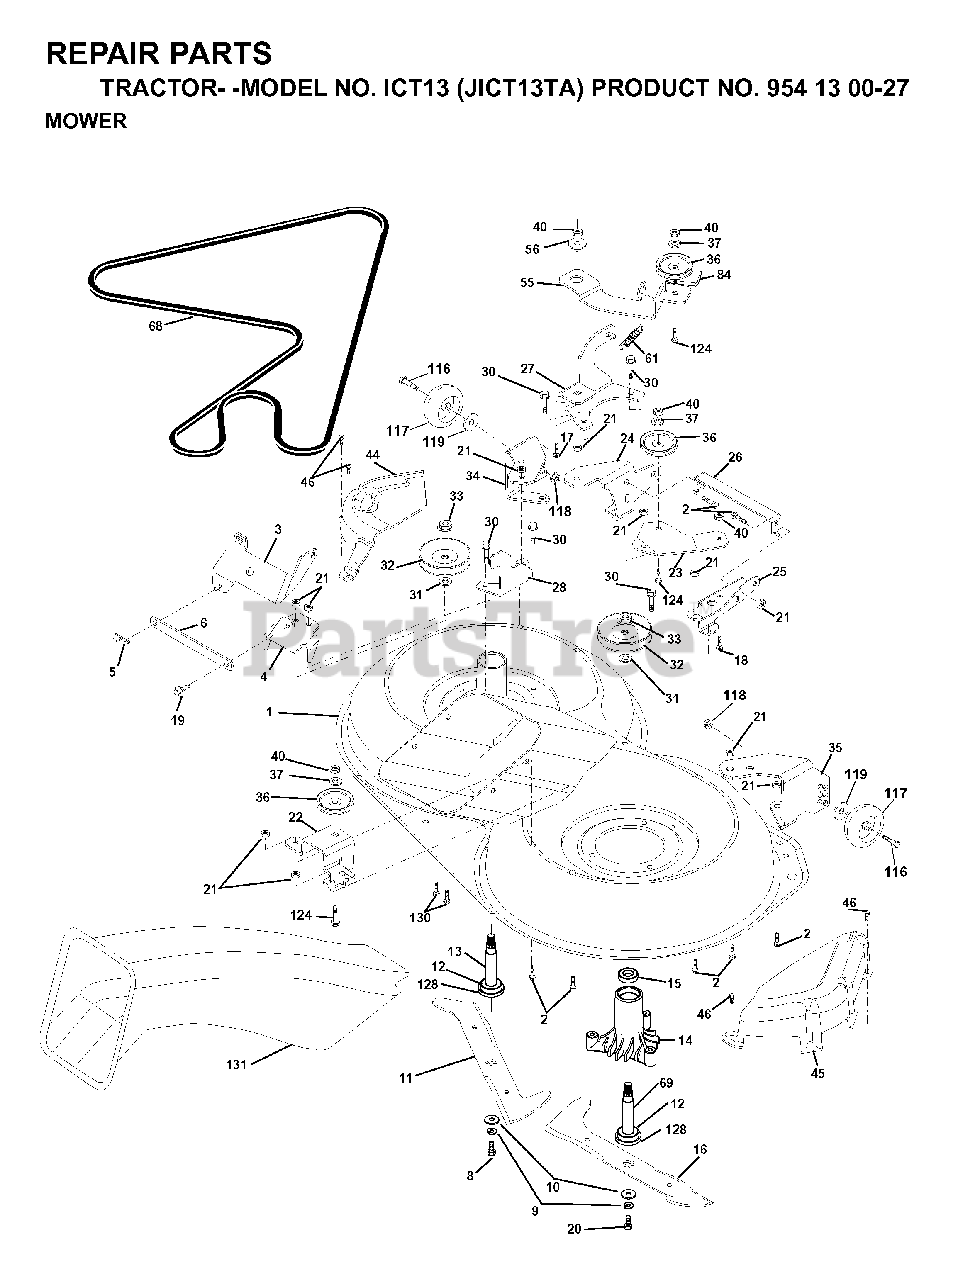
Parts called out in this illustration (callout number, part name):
1	MOWER HOUSING, DECK
2	BOLT
3	BRACKET
5	RETAINER-SPRNG RB
6	BAR SWAY
8	BLADE BOLT
9	LOCKWASHER
10	WASHER.BLADE
11	BLADE
12	BEARING
13	SHAFT ASM VENT
14	HSG MANDREL
16	BLADE
17	BOLT.3/8-14X1.25
19	BOLT SHD 5/16-18
21	LOCKNUT
24	BRACKET
25	BRACKET
26	BRACE
28	BRACKET
30	SCREW THDROL ROLLING WASHER HD
31	WASHER
32	PULLEY, MANDREL
33	NUT
36	PULLEY.IDLER.4.25
40	LOCKNUT
45	COVER
46	SCREW.1/4-20X5/8
55	ARM IDLER
56	SPACER RETAINER
61	SPRING.TENSION.BELT
68	HEX-BELT 92 MOWER 105AA
69	SHAFT.ASM.W/LWR.BRG.RH.THREAD
84	KEEPER, BELT IDLER
116	BOLT, SHOULDER
117	WHEEL GAGE DONUT
118	LOCKNUT
119	WASHER
124	BOLT.3/8-16X1.50
128	WASHER FELT
131	CHUTE BAGGER
